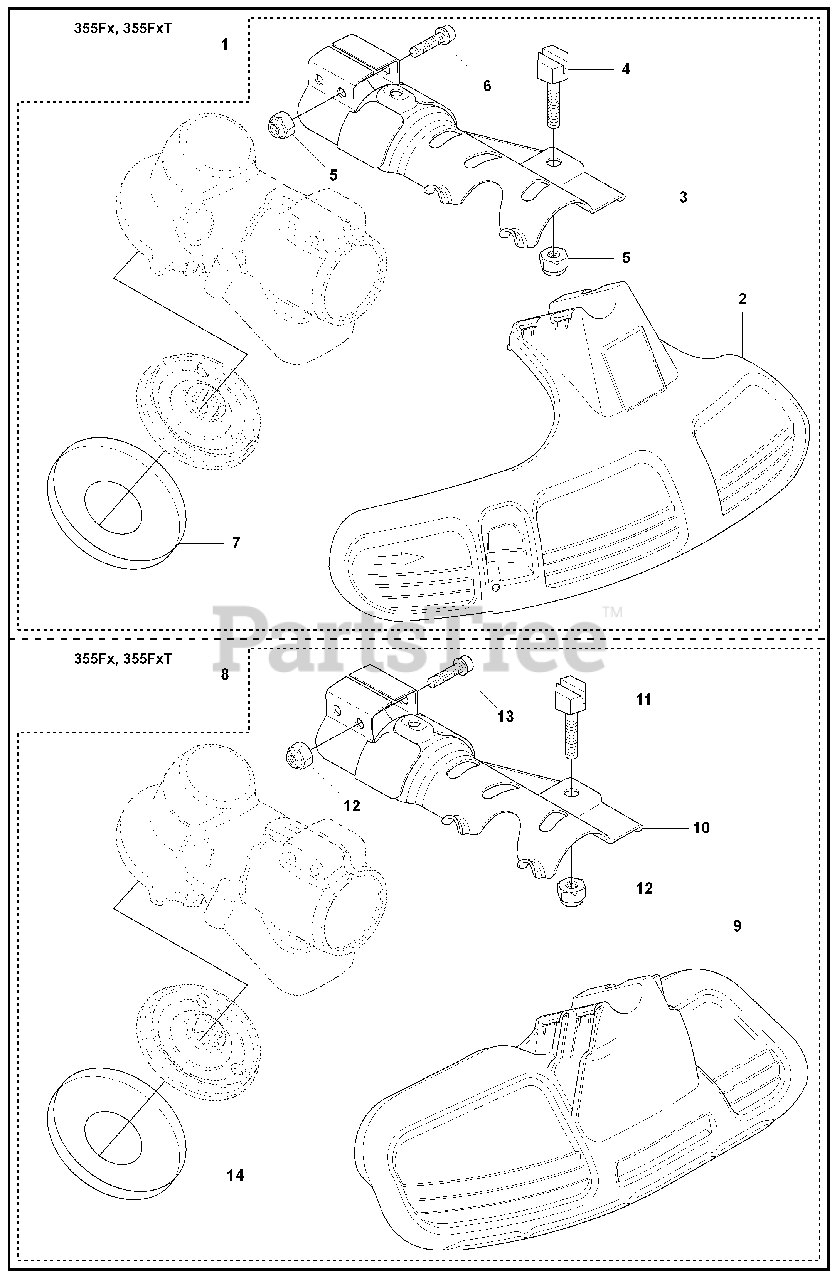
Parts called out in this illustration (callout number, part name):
1	GUARD ASSY
2	PROTECTION
3	ATTACHMENT PLATE
5	LOCKNUT M6
7	GRASS SEALING
8	METAL GUARD
9	BLADE GUARD GRASS
10	ATTACHMENT PLATE
12	LOCKNUT M6
14	GRASS SEALING
